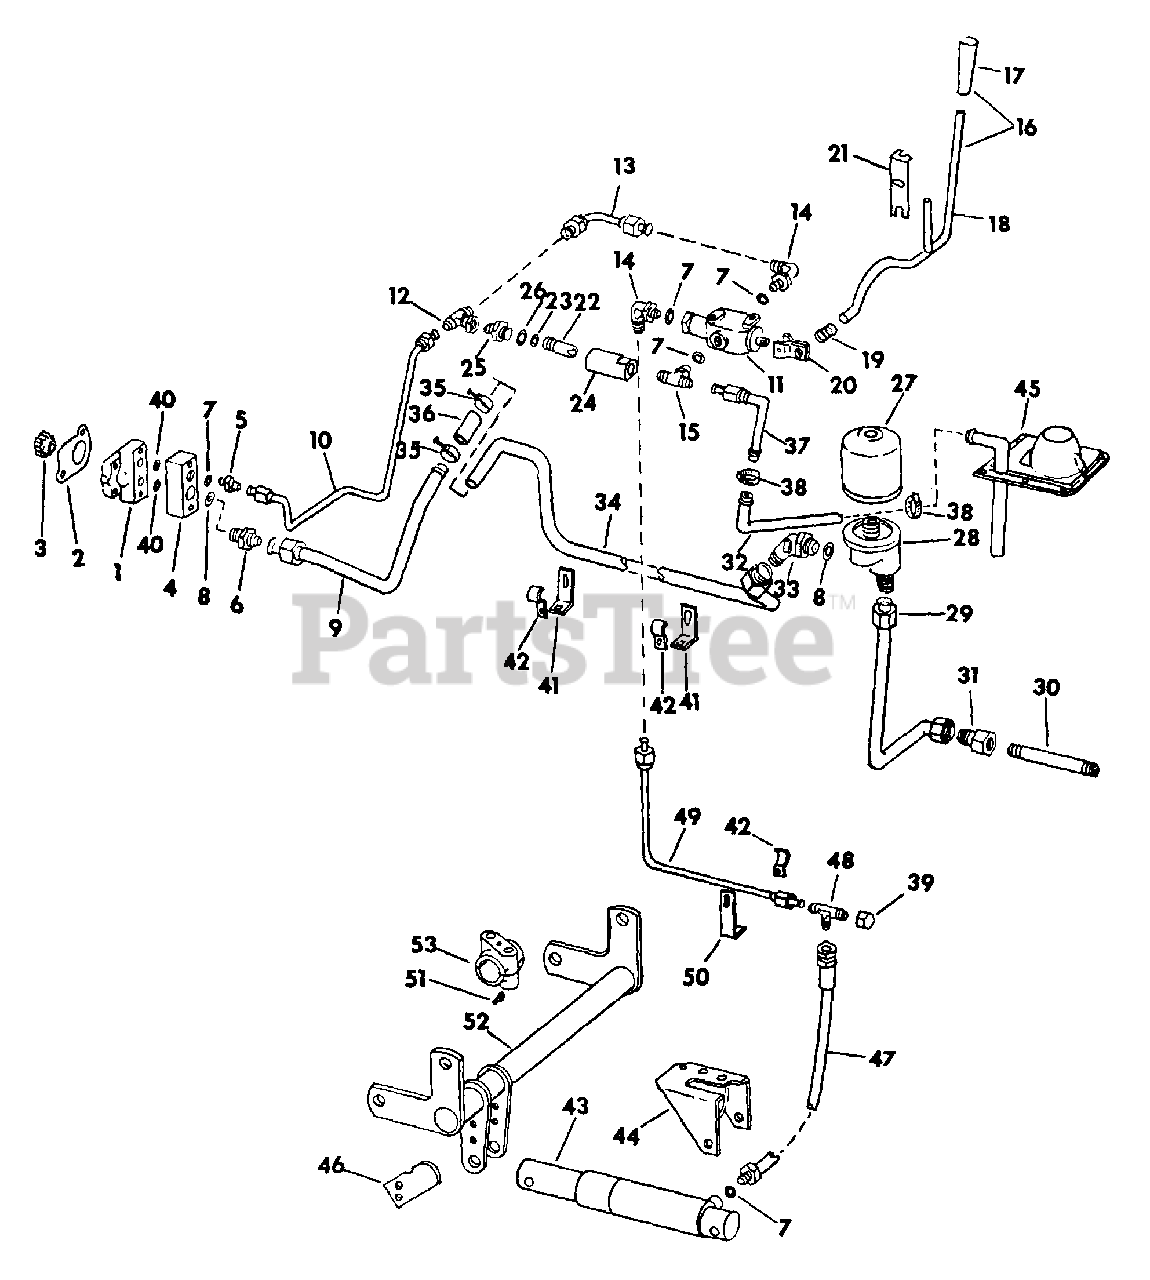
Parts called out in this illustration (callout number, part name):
1	PUMP ASSY, HYDRAULIC (WARNER MOTIVE)
2	GASKET, PUMP
3	GEAR, PUMP DRIVE - 10T
4	FLANGE, HYD PUMP
5	UNION, 9/16-18 C-Z 37 DEG HYD FLARED TUBE SHORT SWIVEL
6	UNION, 1-1/16-12 C-Z 37 DEG HYD FLARED TUBE SHORT SWIVEL
7	O-RING, 3/8 OD TUBE
8	O-RING, 3/4 OD TUBE
9	TUBE ASSY, SUCTION SHORT
10	TUBE ASSY, PRESSURE LONG
11	VALVE ASSY, SINGLE ACTING CONTROL
12	TEE, 9/16-18 37 DEG HYD FLARED TUBE 90 DEG SWIVEL
13	TUBE ASSY, PRESSURE SHORT
14	ELBOW, 9/16-18 37 DEG HYD FLARED TUBE ADJ STR THD 90 DEG
15	TEE, 9/16-18 37 DEG HYD FLARED TUBE ADJ STR THD
16	HANDLE W/GRIP, VALVE
19	SPRING, VALVE HANDLE
20	BAR ASSY, HYD VALVE OPERATING
21	LOCATOR, VALVE HANDLE
22	VALVE ASSY, SAFETY 1500 PSI
23	O-RING, 3/8 X 9/16 X 3/32 SAFETY VALVE
24	HOUSING, SAFETY VALVE
25	CONNECTOR, HYD TUBE REDUCING
26	O-RING, 3/4 X 15/16 X 3/32
27	FILTER ASSY, HYD OIL-SPIN-ON
28	BASE, HYD OIL FILTER
29	TUBE ASSY, HYD FILTER SUCTION
30	NIPPLE, 1/2 X 5-1/2 PIPE
31	CONNECTOR, HYDRAULIC FLARED TUBE
32	HOSE, RETURN
33	ELBOW, 1-1/16-12 C-Z 37 DEG HYD FLARED TUBE ADJ 45 DEG
34	TUBE ASSY, SUCTION LONG
35	CLAMP, SUCTION TUBE HOSE
36	HOSE, SUCTION TUBE
37	TUBE ASSY, RETURN
38	CLAMP, RETURN HOSE
39	CAP, 9/16-18 37 DEG HYD FLARED TUBE
40	O-RING, 5/8 X 13/16 X 3/32 HYD PUMP FLANGE
41	SUPPORT, TUBE CLAMP
42	CLAMP, HYDRAULIC TUBES
43	CYLINDER ASSY, HYD 1-3/4 X 5
44	BRACKET ASSY, CYL MTG
45	HOUSING ASSY, GEAR SHIFT LEVER
46	BAR, ROCKSHAFT STOP
47	HOSE ASSY, HYDRAULIC
48	TEE, 9/16-18 37 DEG HYD FLARED TUBE THREE WAY
49	TUBE ASSY, HYDRAULIC CYLINDER
50	SUPPORT, TUBE CLAMP
51	FITTING, 3/16 65 DEG ANGLE DRIVE TYPE LUB
52	ROCKSHAFT ASSY
53	BEARING ASSY, ROCKSHAFT
